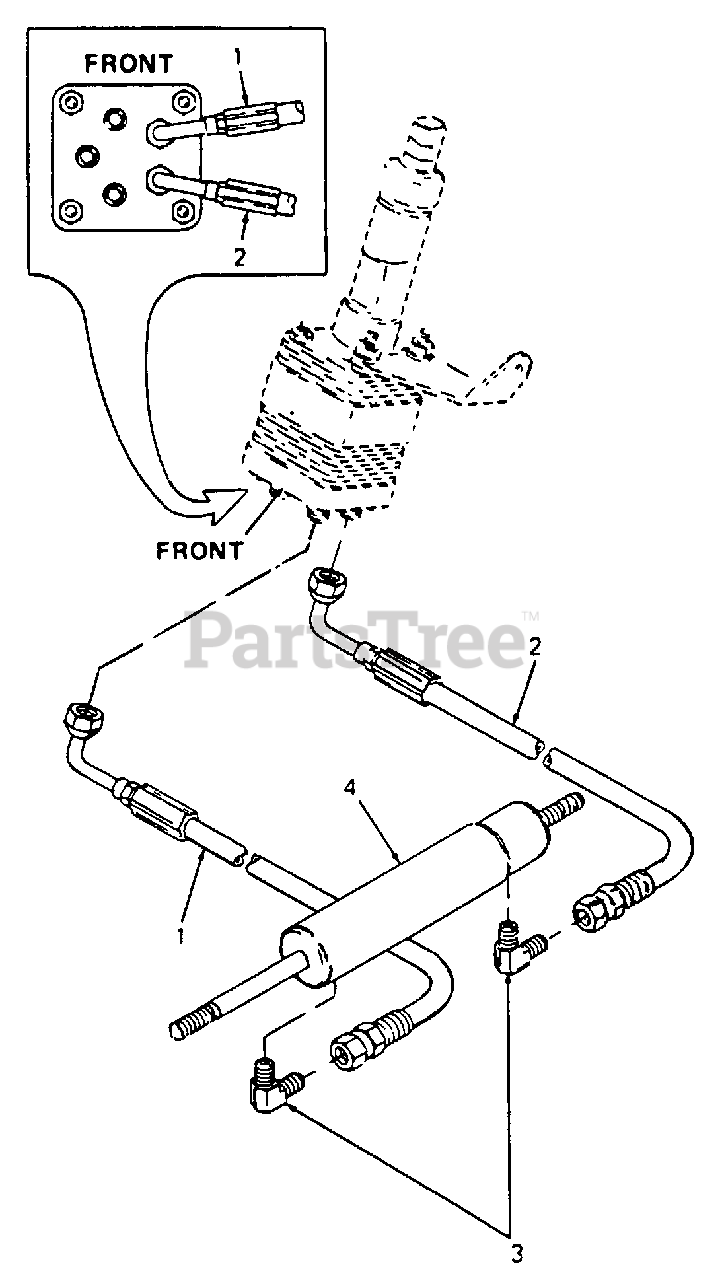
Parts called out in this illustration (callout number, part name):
1	Hose, Steering, 10.5 Lg
2	Hose, Steering, 8.9 Lg
3	Elbow, 90 Deg Tube
